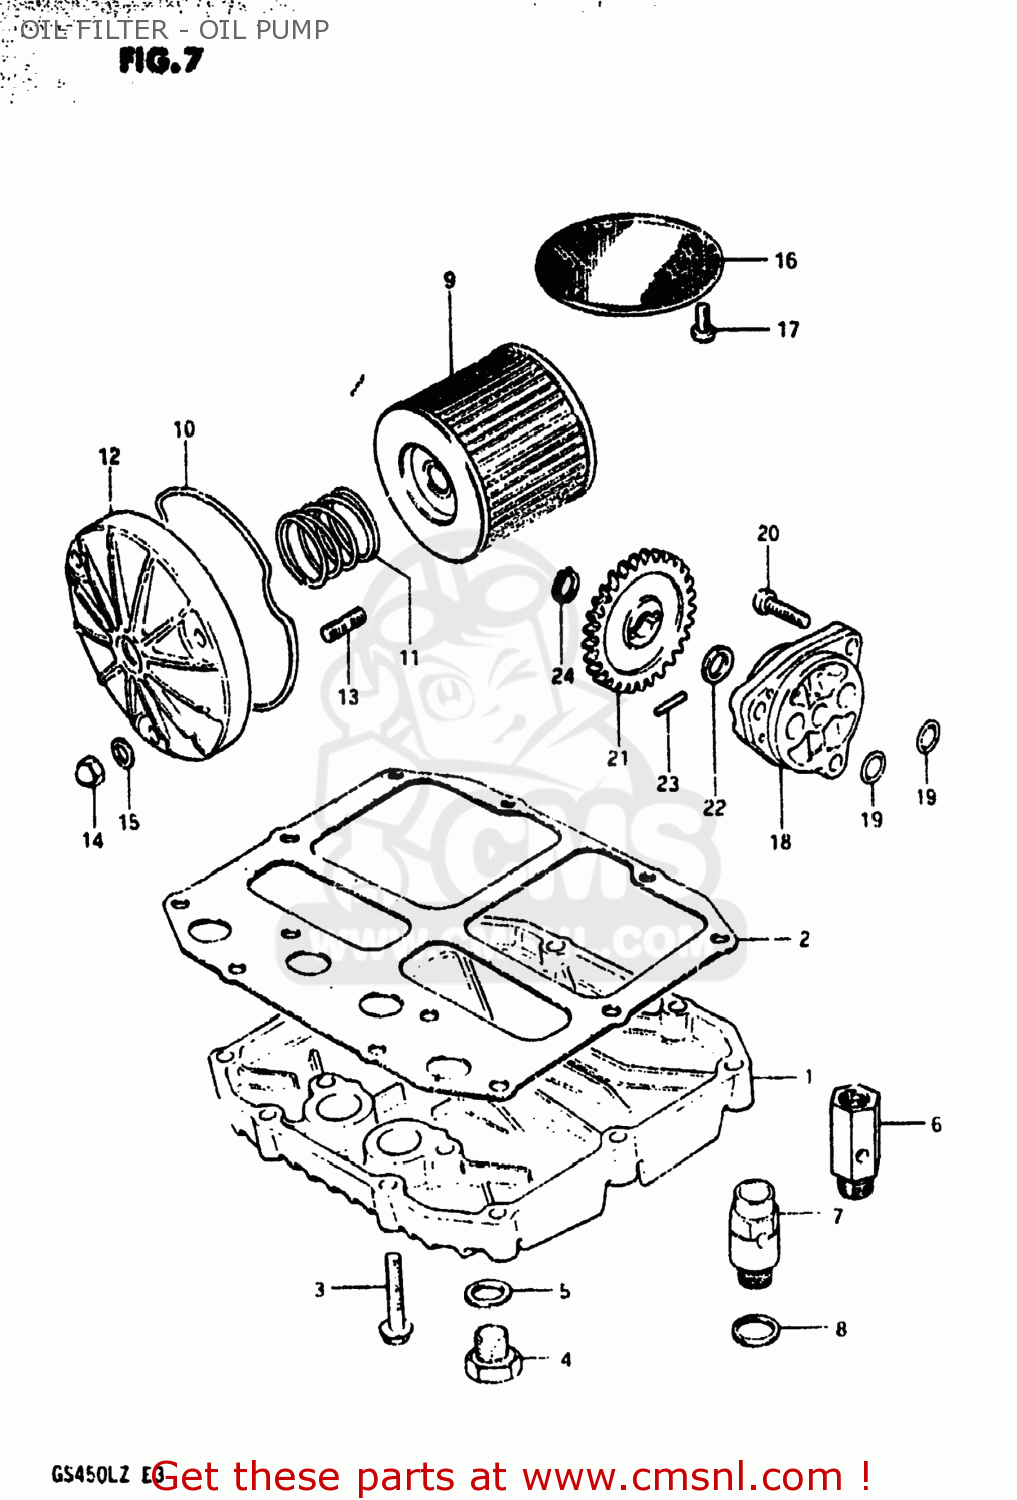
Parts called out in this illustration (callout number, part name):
1	PAN,OIL
2	GASKET,OIL PAN (MCA)
3	BOLT
4	PLUG
5	GASKET(14X19.2X2) (NAS)
6	REGULATOR ASSEMBLY,ENGINE
7	REGULATOR ASSEMBLY,ENGINE
8	WASHER
9	FILTER ASSY,ENGINE OIL
10	O RING,OIL FILTER CHAMBER CAP
11	SPRING
12	CAP,OIL FILTER
13	STUD 6X20
14	NUT
15	WASHER
16	STRAINER,ENGINE OIL
17	SCREW 6X12
18	PUMP ASSY,ENGINE OIL
19	O RING(D:1.9,ID:13)
20	SCREW
21	GEAR,OIL PUMP DRIVEN
22	SHIM
23	PIN(4X15.8)
24	CIRCLIP
